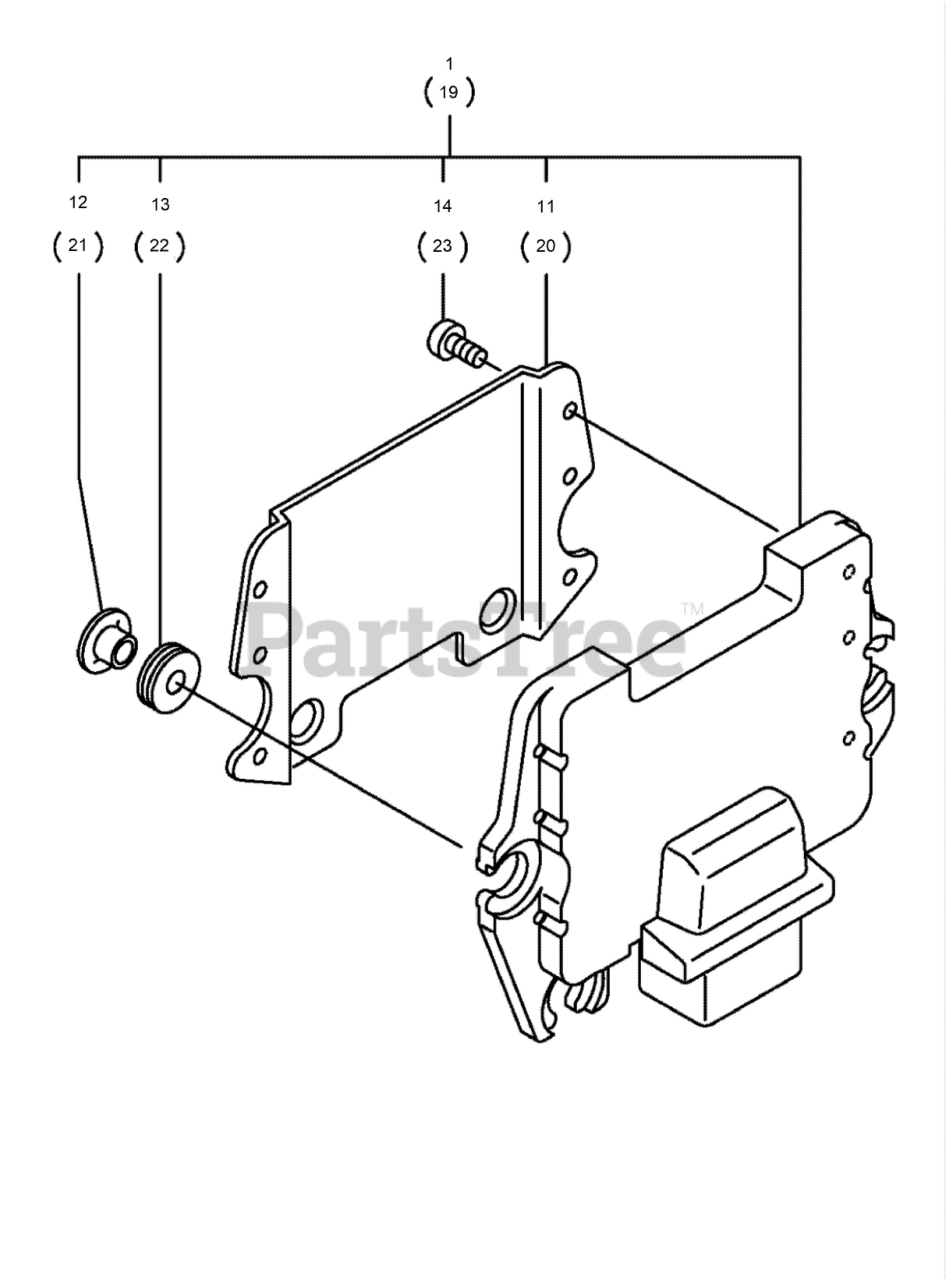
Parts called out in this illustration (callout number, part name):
1	ECU ASSY,380FT-ZMTR2
11	SHIELD
12	COLLAR
13	ABSORBER
19	CONTROLLER-ENGINE
20	SHIELD
21	COLLAR
22	ABSORBER
